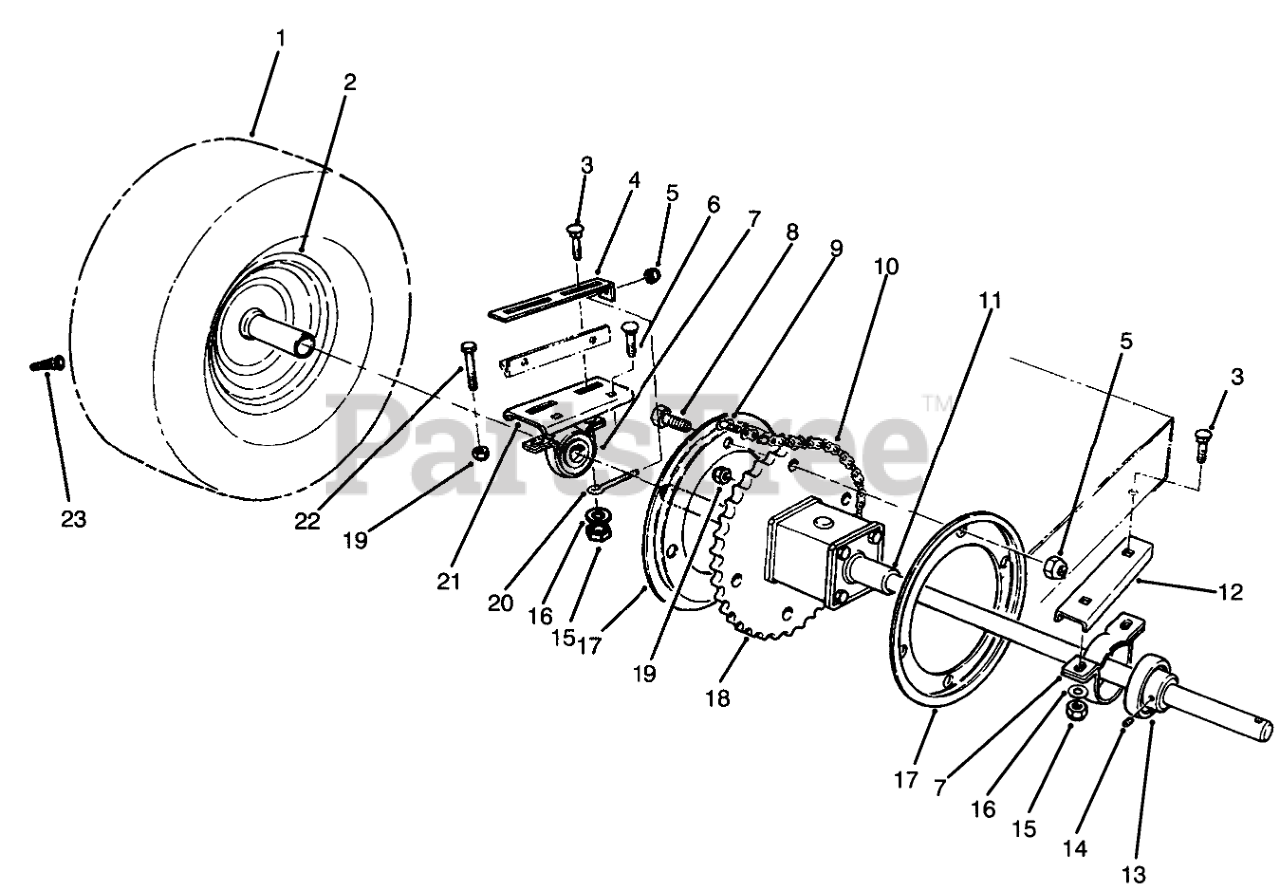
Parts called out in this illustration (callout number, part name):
1	TIRE,PNEU.13X5.00X6
2	WHEEL-REAR
3	SCREW-CARR
4	PLATE-ADJUSTING
5	NUT-LOCK, NI
6	BOLT-CARR
7	RTNR-PILLOW BLK
8	SCREW-HH
9	LINK-CHAIN
10	Chain (Incl. Ref. #9)
11	DIFFERENTIAL
12	LH AXLE SUPPORT (BLACK)
13	Bearing (Incl. Ref. #14)
14	SCREW-HSH
15	NUT-LOCK, NI
16	WASHER-FLAT
17	GUIDE-REAR CHAIN
18	SPROCKET
19	NUT-LOCK, NI
20	SCREW-ADJUSTING
21	RH AXLE SUPPORT (BLACK)
22	AXLE MTG BOLT
23	STEM-VALVE
